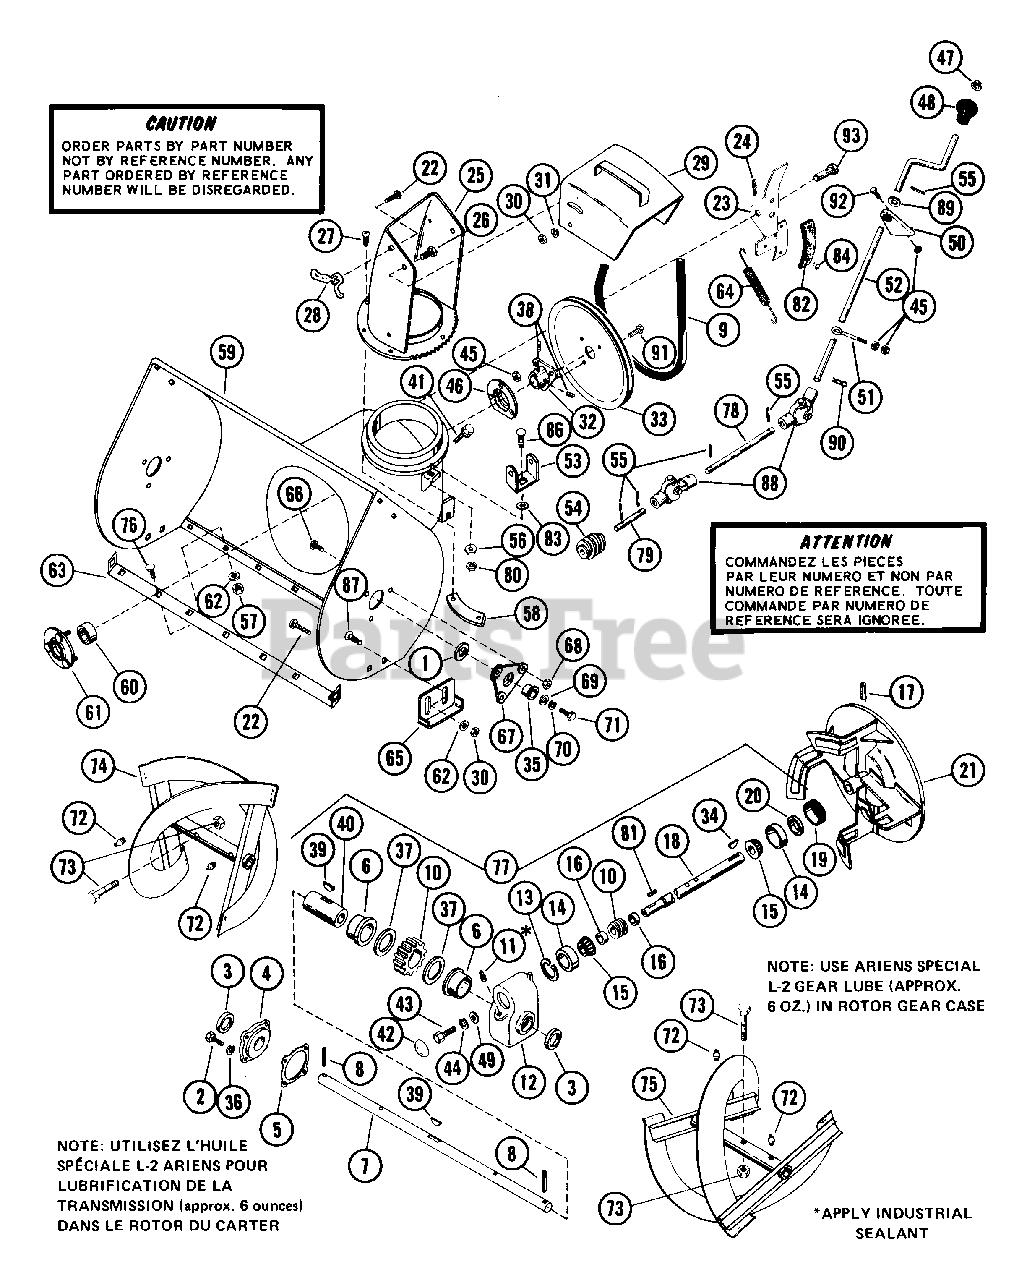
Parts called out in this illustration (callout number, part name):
1	WSHR-FL-STL 1.010X1.505X.062PL
2	BLT-HEX .25-20X.75 PL GR2
3	SEAL 1.625X2.125X.250
4	GEAR CASE COVER
6	BSHG-FLG .683X1.87X1.68X2.250
7	SHAFT, 32" RAKE - 1.00 DIA.
8	PIN-ROLL .188X1.50
9	V-BELT, 4L-RAW EDGE
10	WORM & GEAR SERVICE ASSEMBLY
11	PIPE PLUG
12	GEAR CASE - CAST IRON
13	RG-RTNG INT 1.781 HSG X.062
14	BRG-CUP 1.781X.475
15	BRG-CONE .750X.61
16	BSHG, SPCR .755X1.12X.50 PM
17	PIN-ROLL .313X1.75
18	SHAFT, WORM - 1.00 DIA.
19	ADJUSTMENT PLUG - 1" SHAFT
20	SEAL 1.000X1.312X.150
21	FAN, 12"
22	BLT-RDHDSQNK .38-16X.75 SHT PL
23	BRAKE ARM ASSEMBLY
24	PIN-HAIR INT .06X.18X.77
25	DISCHARGE CHUTE
26	BLT-HEX .38-16X.75 PL GR2
27	SCR-TAP 10-24X.375 HWH PL TR
28	WING NUT
29	SERVICE DEFLECTOR ASSM
30	NUT-LK-CTR .375-16 GR A PL
31	WSHR-LK .375X.115 HVY PL
32	PULLEY HUB
33	PLY-V 9.0 X 1.25 3BLT
34	KEY-WDRF .188X.875X.375 SAE11
35	BSHG-FLG 1.000X1.12X.62X1.50BR
36	WSHR-LK-EXT. 250 ID
37	WSHR-FL-STL 1.625X2.500X.012
38	SCR-SET .32-18X.38 SKHCUPNL OH
39	KEY-WDRF .25X.875X.375 SAE A
40	GEAR CASE SHAFT
41	BLT-SCRHFWH .38-16X.75 PL
42	DUST CAP
43	BLT-HEX .31-18X.75 PL GR2
44	WSHR-LK .312X.097 PL HVY
45	NUT-LK-CTR .250-20 PL
46	BEARING FLANGE
47	CAP, 3/8 ROD YWZC
49	WSHR-FL-STL .328X1.0X.094
50	ROD HANGER
51	EYEBOLT
52	CRANK, CHUTE
53	WORM CLEVIS
54	WORM GEAR
55	PIN-ROLL .125X.75
56	WSHR-LK .313X.062
57	NUT-LK .312-18 GR A PL
58	CHUTE CLAMP
59	32 IN BLOWER HOUSING ASSY
60	BRG-BALL .750X1.750X.50
61	BEARING FLANGE
62	WSHR-FL-STL .38X.875X.083 PL
63	SCRAPER BLADE
64	SG-TENS .062X.56X8.0 WLD 11
65	RUNNER
66	SCR-SLTR-SERNK .25-20X.62 PL
67	BEARING SUPPORT
68	NUT-LK-FLG .250-20 PL
69	WSHR-FL-STL .511X1.441X.125 PL
70	WSHR-LK .500X.151 HVY PL
71	BLT-HEX .50-13X1.00 PL GR2
72	SPIN DRIVE ZERK FITTING
73	SHEAR BOLT SERVICE ASSEMBLY
74	RAKE, RIGHT-32"(1ID X 15.75OD)
75	RAKE, LEFT-32"(1"ID X 15.75OD)
76	BLT-RDHDSQNK .312-18X.62 PL
77	GEAR CASE - CAST IRON
79	WORM SHAFT
80	NUT-HEX .312-18
81	KEY-SQ .188X1.0X.188 SAE 8630
82	BRAKE LINING
83	WSHR-LK-EXT .313X.030 PL
84	RVT-TBLR .187X.375 OH ST PL
86	BLT-RDHDSQNK .31-18X.75 GR5 PL
87	BLT-RDHDSQSHNK .38-16X1.00 PL
88	UNIVERSAL JOINT ASSY
89	WSHR-FL-STL.406X.812X.065PL
90	PIN-HAIR INT .08X.38X1.42 YWZC
91	BLT-SERHFWH .31-18X.62 PL
92	BLT-HEX .25-20X.50 PL GR2
93	CLEVIS PIN
